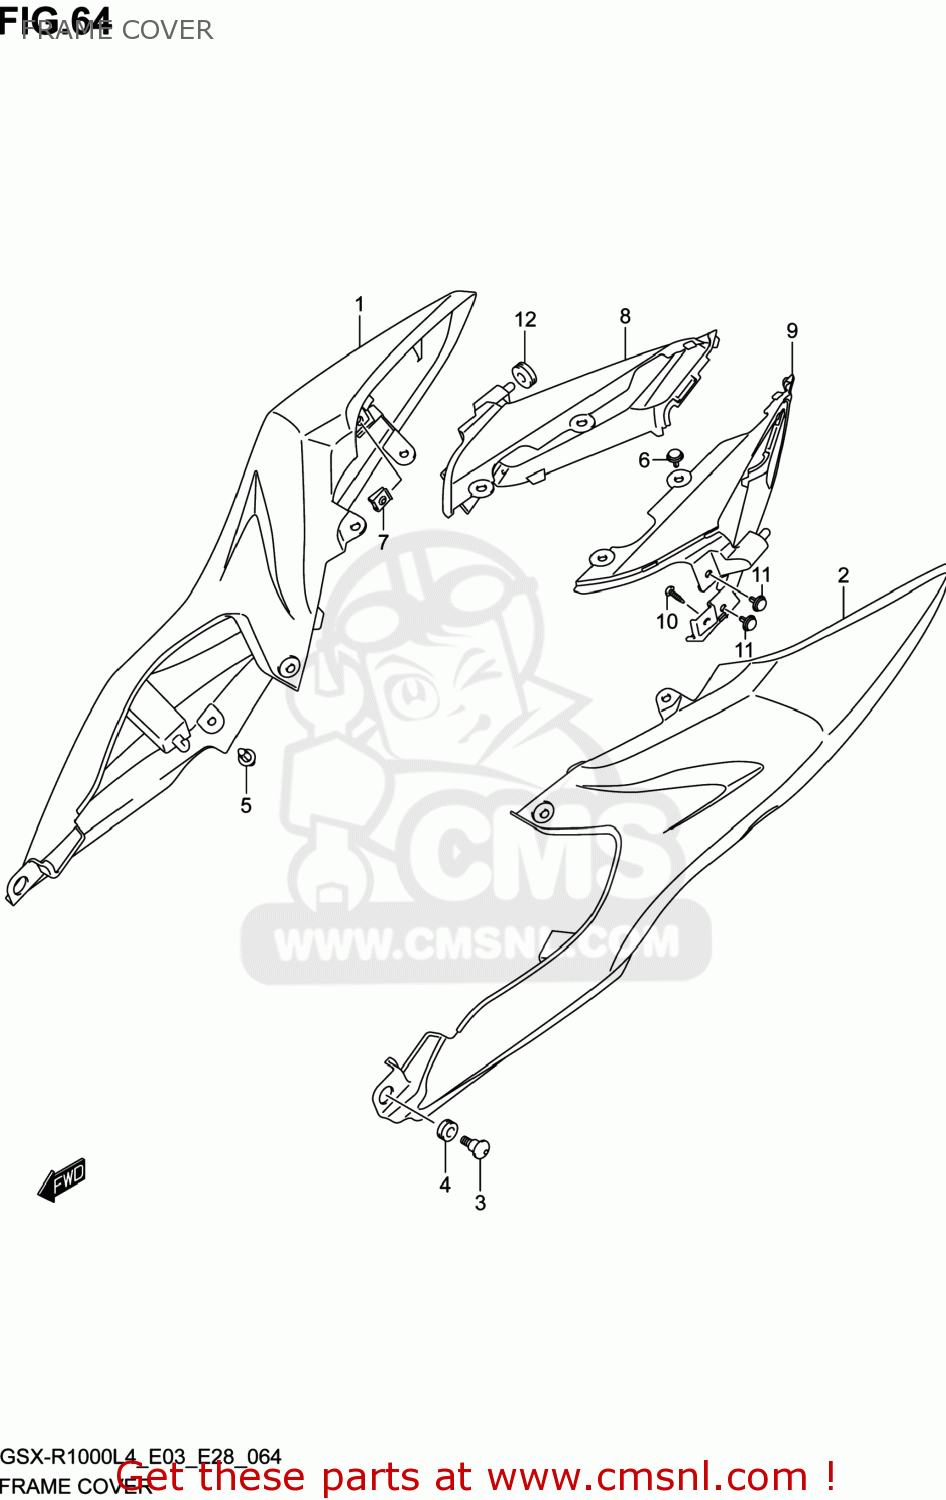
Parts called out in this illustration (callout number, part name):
1	COVER,FRAME,R(WHITE)
2	COVER,FRAME,L
3	SCREW,SIDE COVER LWR,R
4	CUSHION
5	CLIP(BLACK)
6	CLIP
7	NUT
8	COVER,FRAME RR,R
9	COVER,FRAME RR,L
10	SCREW
11	CLIP
12	CUSHION
